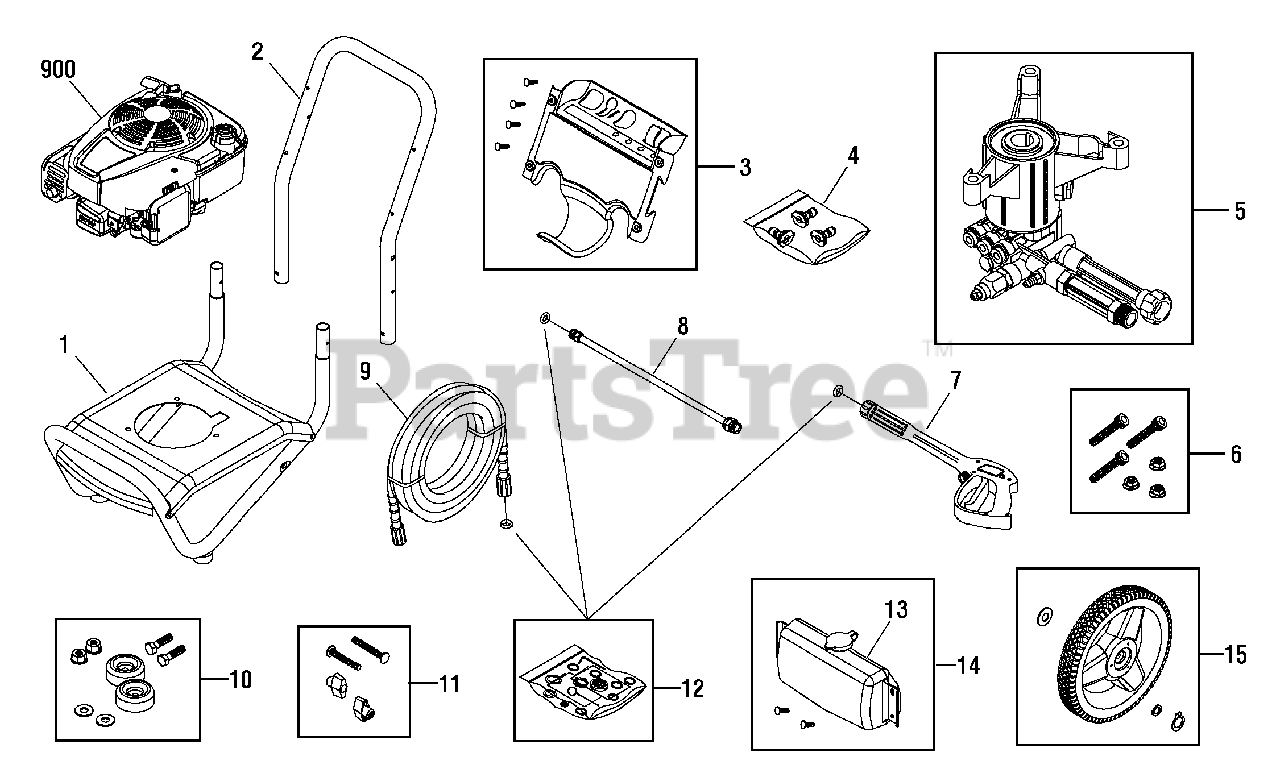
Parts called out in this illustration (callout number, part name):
4	KIT, QC Nozzles
6	KIT, Hardware, Pump Mounting
7	GUN
8	EXTENSION, QC
9	HOSE
10	MOUNT, Vibration
11	KIT, Hardware, Handle
12	O-RINGS
13	CAP, Chemical Tank
900	* ENGINE
